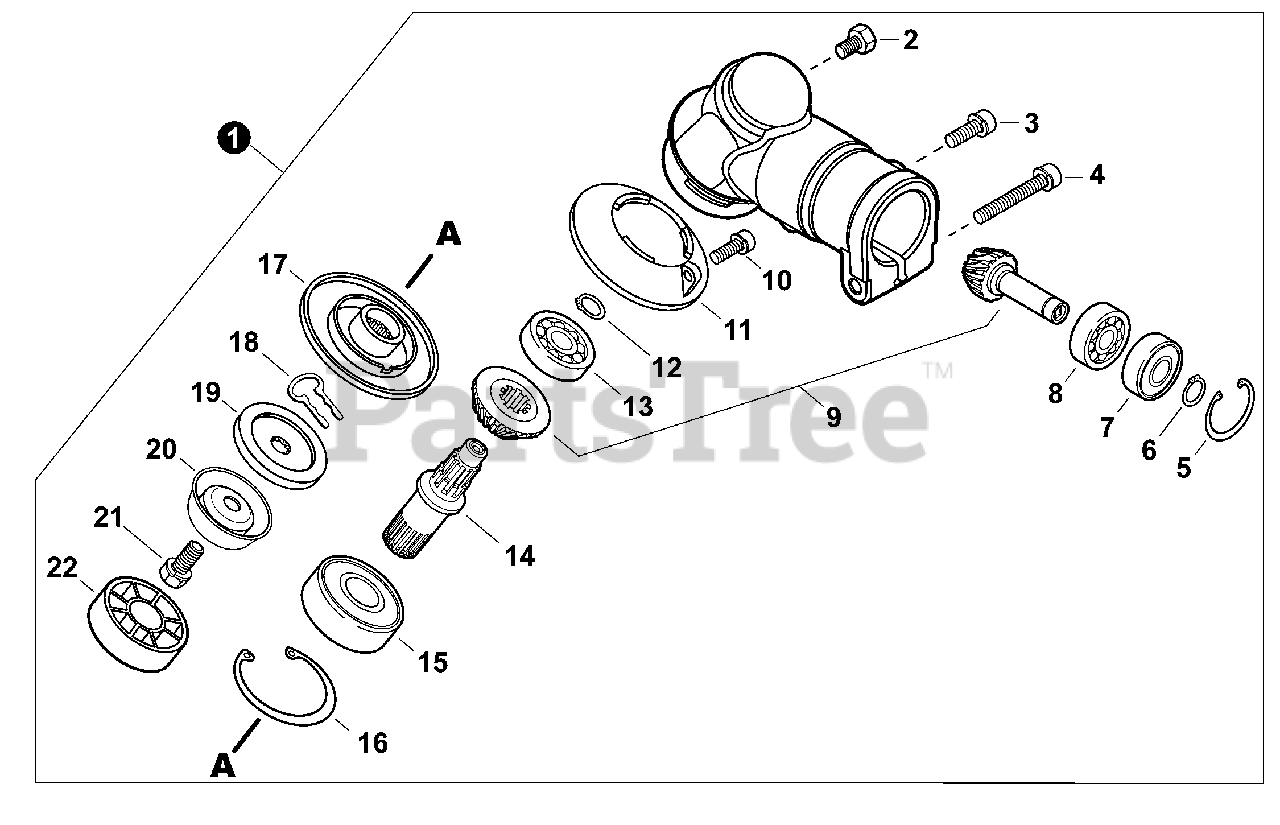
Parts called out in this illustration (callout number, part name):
1	GEAR CASE ASSY
2	BOLT M8×8
3	SCREW 5×12
4	BOLT M5×35
5	RING, SNAP 24
6	RING, SNAP Ø9
7	BEARING, BALL 609
8	BEARING, BALL 609
9	GEAR SET
10	BOLT 5×12
11	COVER, GEAR CASE
12	RING, SNAP Ø6
13	BEARING, BALL 626 DDU
14	SHAFT, GEAR
15	BEARING, BALL 6000DDU
16	RING, SNAP 26
17	PLATE, ADAPTOR - UPPER
18	CLIP, BLADE
20	GUARD, BOLT
21	BOLT M7×1.0×26
22	SPACER, BLACK
